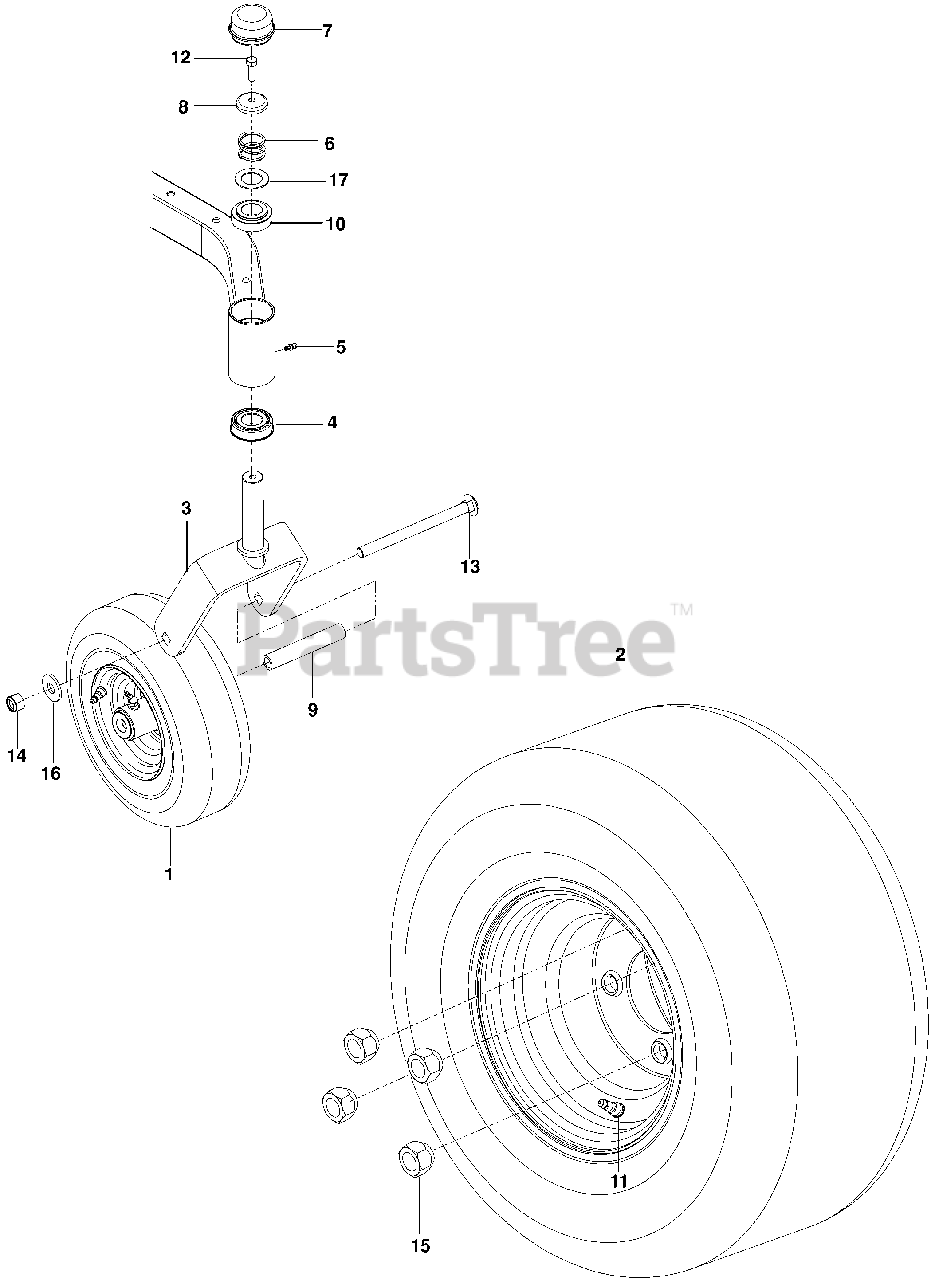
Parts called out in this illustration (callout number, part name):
4	BEARING FLANGED
5	ZERK, 3/16, DRIVE IN
6	SPRING, CASTER
7	GREASE CAP
8	CASTER.PLUG
9	SPACER, PIVOT
10	BUSHING, CASTER
11	VALVE STEM TR-412
12	5/16-18X1 HHB G5W/NY
13	RHSNB 1/2-13 X 7.5
14	NUT 1/2-13 HEX CNTRLK GR 5 ZD
15	LUG NUT 1/2F
16	WASH USS FLAT 1/2
17	WASHER, 1.025 ID X 1.64
